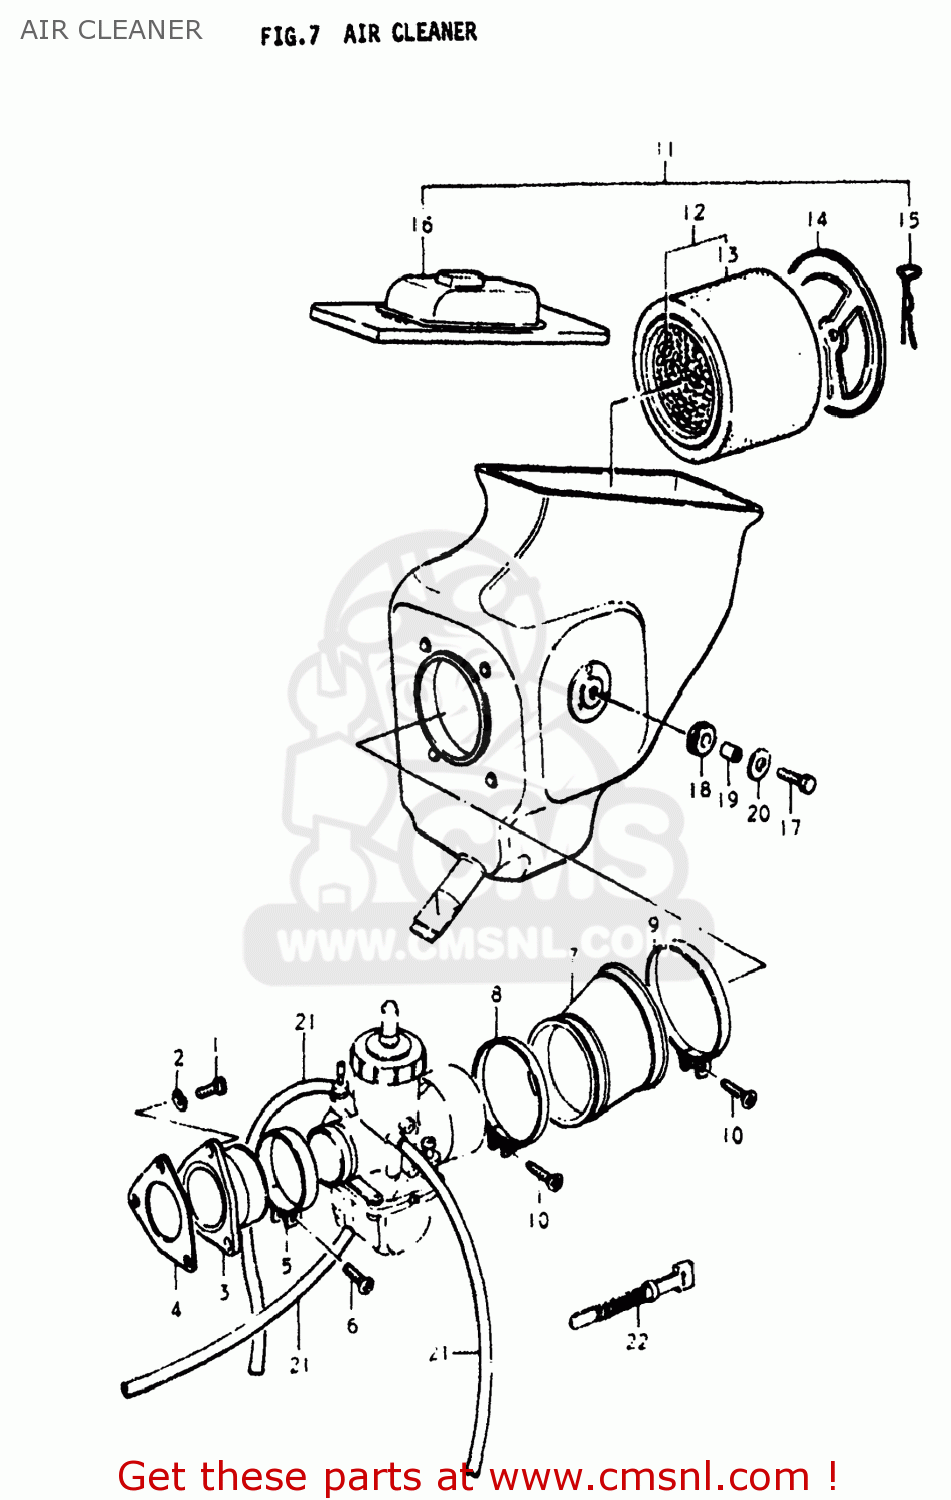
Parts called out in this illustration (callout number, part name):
1	BOLT, UPPER
2	LOCK WASHER
3	PIPE,INTAKE
4	GASKET,INTAKE PIPE (NAS)
5	CLAMP
6	SCREW 5X20
7	HOSE,CARBURETOR AIR INLET
8	CLAMP
9	CLAMP
10	SCREW
11	CLEANER ASSEMBLY,AIR
12	FILTER ASSY
13	FILTER
14	CAP
15	SPRING,AIR CLEANER
17	BOLT, UPPER
18	CUSHION
19	SPACER (7X9X7)
20	WASHER (6.5X20X1.2)
21	HOSE
22	CLAMP(L:120)
